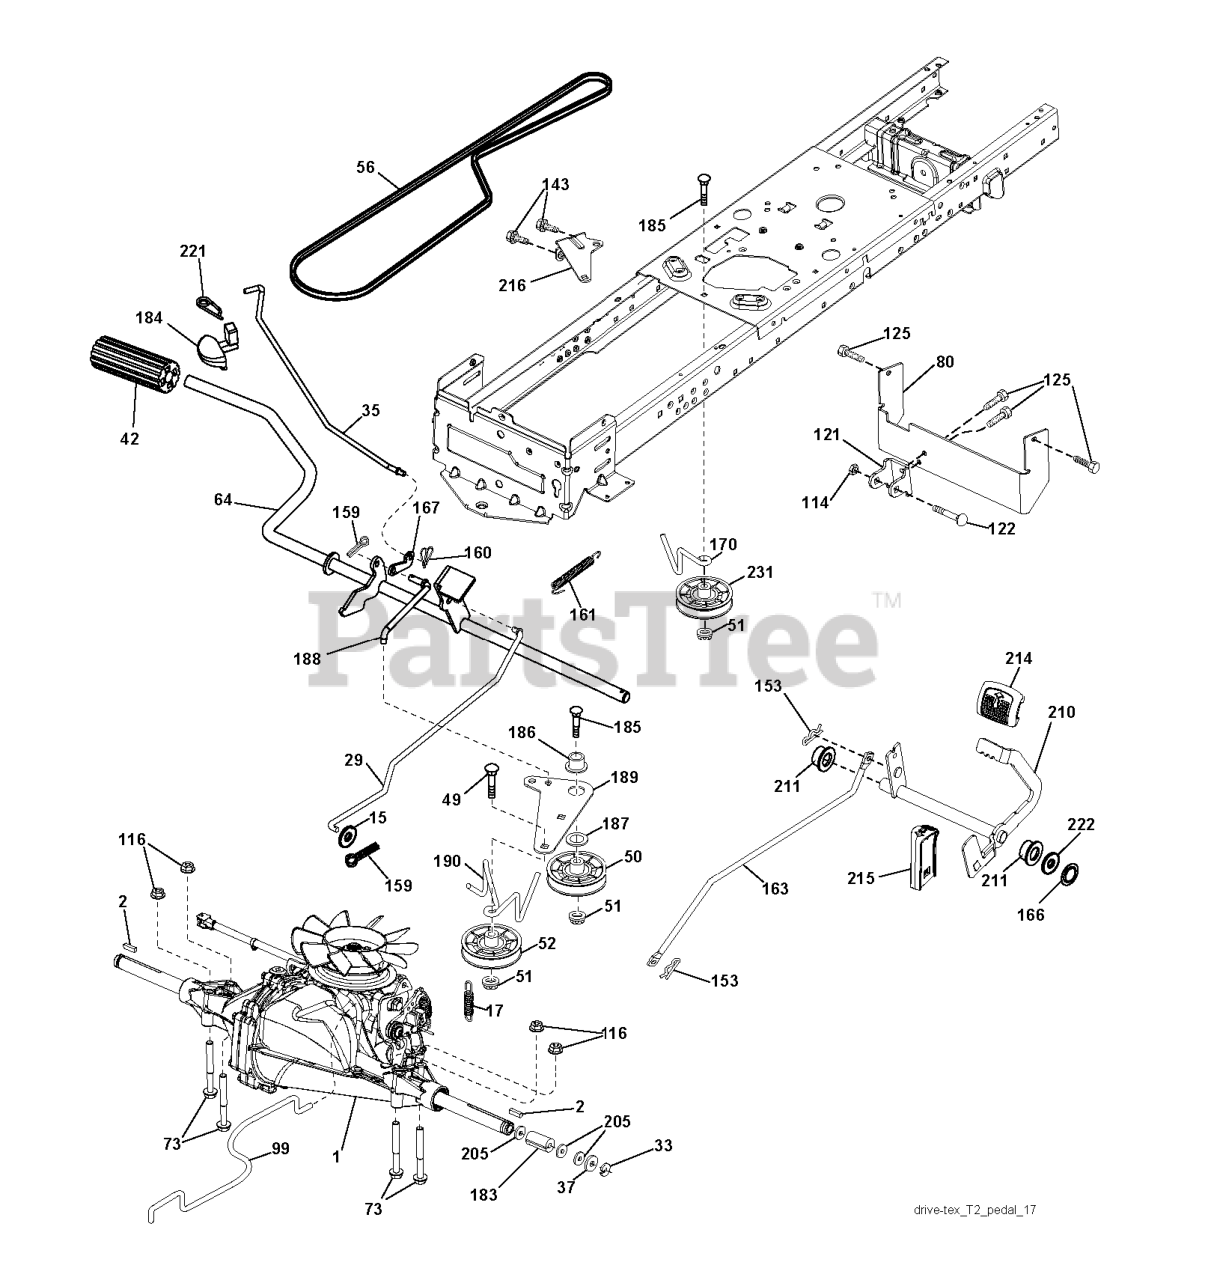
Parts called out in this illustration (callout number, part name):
2	SQUARE KEY
15	WASHER
17	SPRING.BRAKE.HG3000/3500
29	ROD.BRAKE.T2.TEX
35	ROD.CNTRL.PARK.PREDATOR.LT.TEX
42	PEDAL COVER T
50	IDLER.FLAT.910.OFFSET
51	NUT LOCK FLG 3/8-16 UNC
52	IDLER.V-GROOVE.910.OFFSET
64	SHAFT.ASM.PEDAL.BRK.CNTR
73	BOLT HEX 5/16-18 GR 5
80	RP.STRAP.TORQUE.FS.T2
99	ROD.ASM.BYPASS.SPRING.T2.FS
114	NUT.71038.31-18.HEX.NYLOCK
116	NUT LOCK HEX FLANGE 5/16-18
121	BRACKET STRAP TORQUE
122	BOLT.5/16-18X2.5
125	SCREW
143	Screw 5/16-18 x 1/2 Hex, Self Tapping 5/16-18 x 1/2
153	RETAINER M
159	COTTER PIN
160	RETAINER CLIP
161	SPRING, RETURN LT
163	ROD.CONTROL.PCH.T2.TEX
166	NUT.PUSH.625.2006
167	LATCH.BRAKE.SPRING
170	KEEPER.CENTER SPAN.1.688
183	SPACER, AXLE PVST
184	HANDLE PARKING BRAKE
186	SPACER.RETAINER
187	WASHER 12/32X2X10GA
188	RP.LINK.CLUTCH.GROUND.DRIVE
189	BELLCRANK.GROUND.DRIVE.TEX.
190	KEEPER.BELLCRANK.DRIVE
210	ROCKER.ASM.PEDAL.CONTR
211	BEARING.NYLON
214	PEDAL.FORWARD.TEX.GT.4
215	PEDAL.REVERSE.TEX.GT.4
216	BRACKET.PULLEY.IDLER.W/TEX
221	RETAINER.SPRING.CLIP.H
222	WASHER 21/32 X 1-1/4 X 10 GA.
231	IDLER.V-GROOVE.1.688.OFFSET
